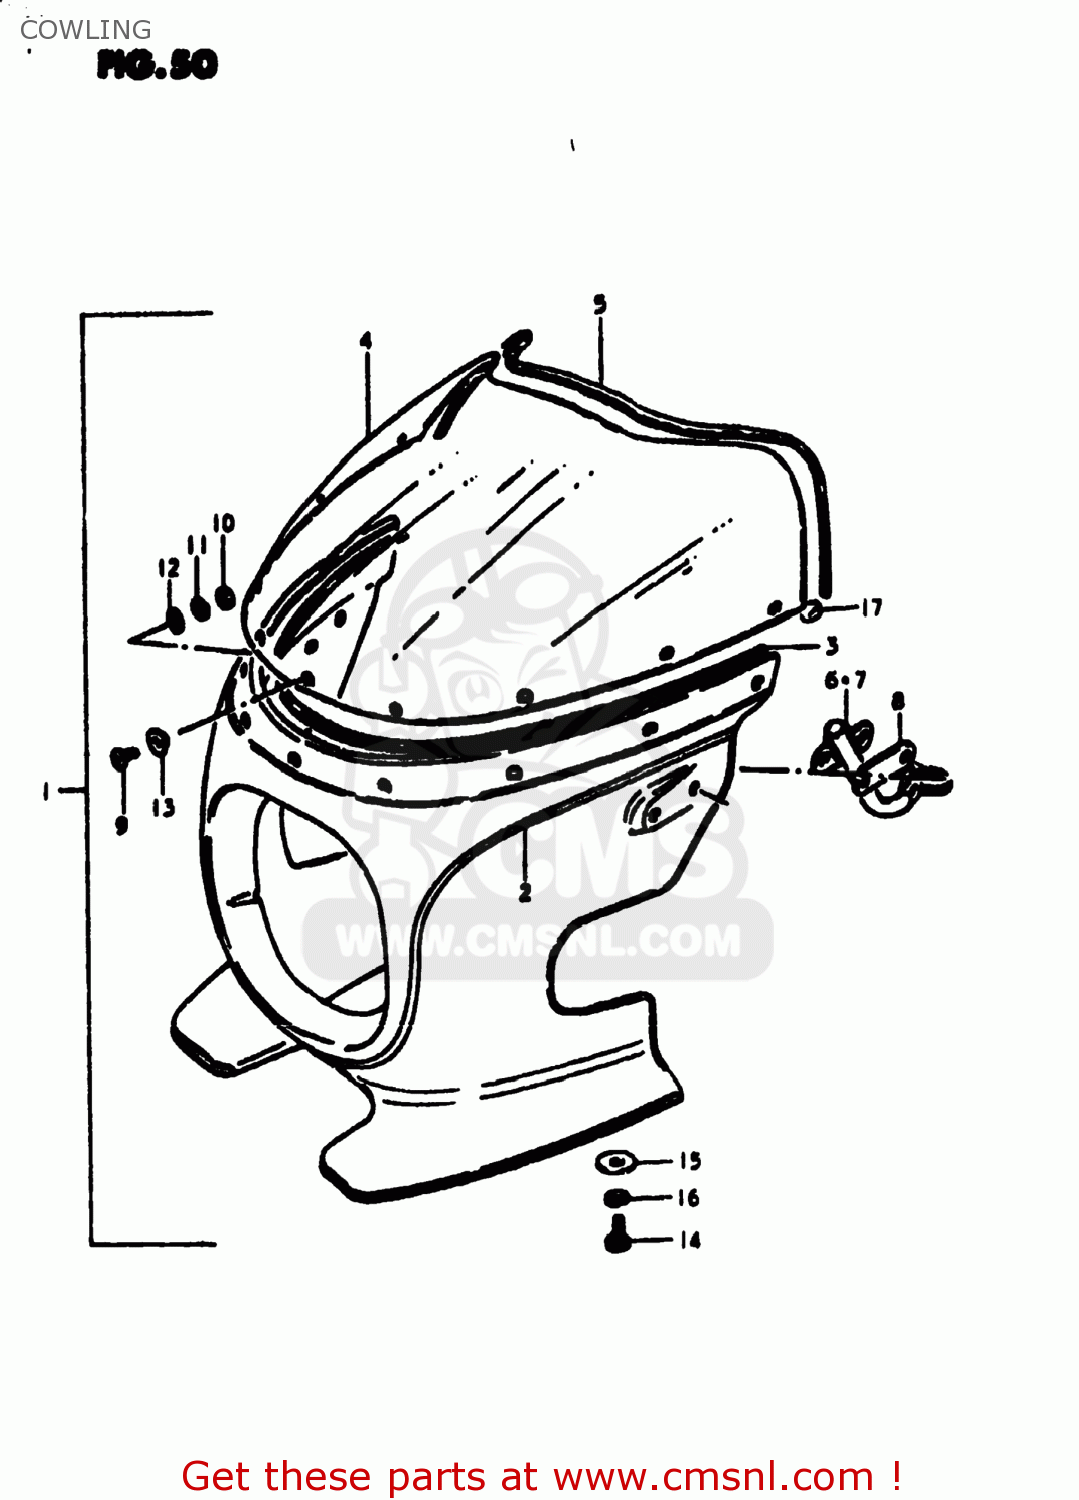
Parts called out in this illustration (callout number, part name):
1	BODY ASSEMBLY,COWLING
2	TAPE SET
3	MOLDING,COWLING
4	WINDOW,COWLING
5	MOLDING,COWLING
6	BRACKET,COWLING,UPPER
7	BRACKET,COWLING,UPPER
8	CUSHION,COWLING
9	SCREW M5X12 DIN 7985/N
10	NUT
11	LOCK WASHER
12	WASHER
13	CUSHION
14	BOLT, UPPER
15	WASHER
16	LOCK WASHER
17	COVER,MOLDING END
